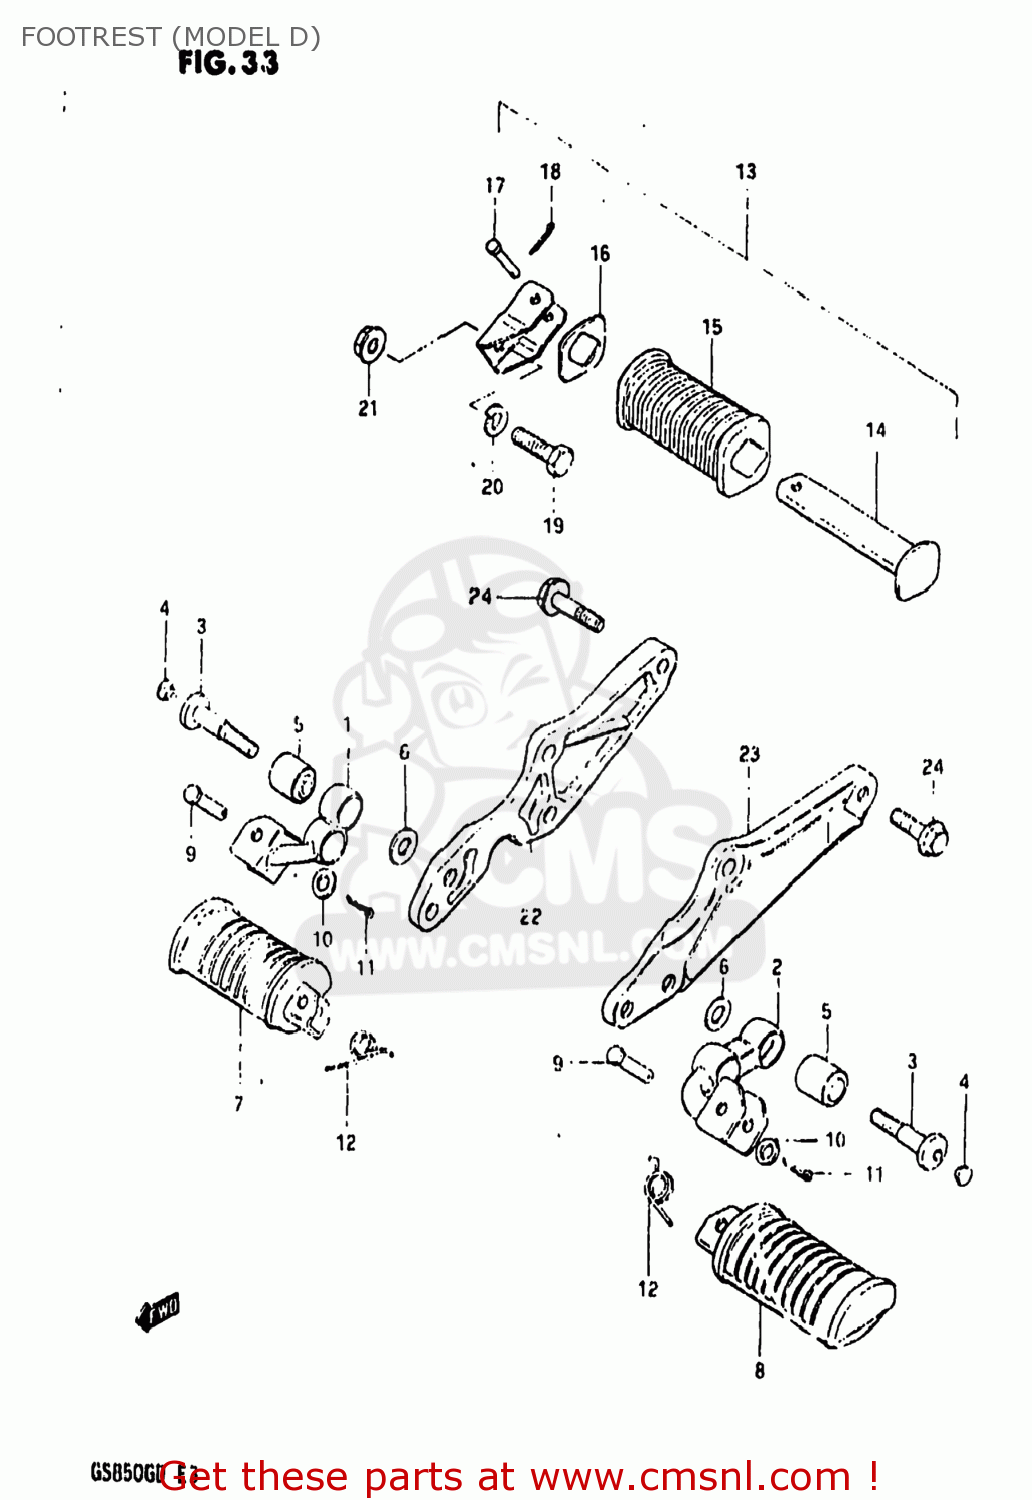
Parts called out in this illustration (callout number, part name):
1	BAR,FRONT FOOTREST,RIGHT
2	BAR,FRONT FOOTREST,LEFT
3	BOLT(10X50)
4	CAP
5	BUSH
6	WASHER
7	RUBBER,PILLION FOOTREST,R
8	RUBBER,PILLION FOOTREST,L
9	PIN
10	WASHER
11	PIN 20X20
12	SPRING
13	FOOTREST ASSEMBLY,REAR
14	BAR,REAR FOOTREST
15	RUBBER,REAR FOOTREST
16	WASHER,REAR FOOTREST RUBBER
17	PIN
18	PIN 20X20
19	BOLT,M10X1.25X
20	LOCK WASHER
21	NUT
22	BRACKET,MUFFLER,RIGHT
23	BRACKET,MUFFLER,LEFT
24	BOLT
